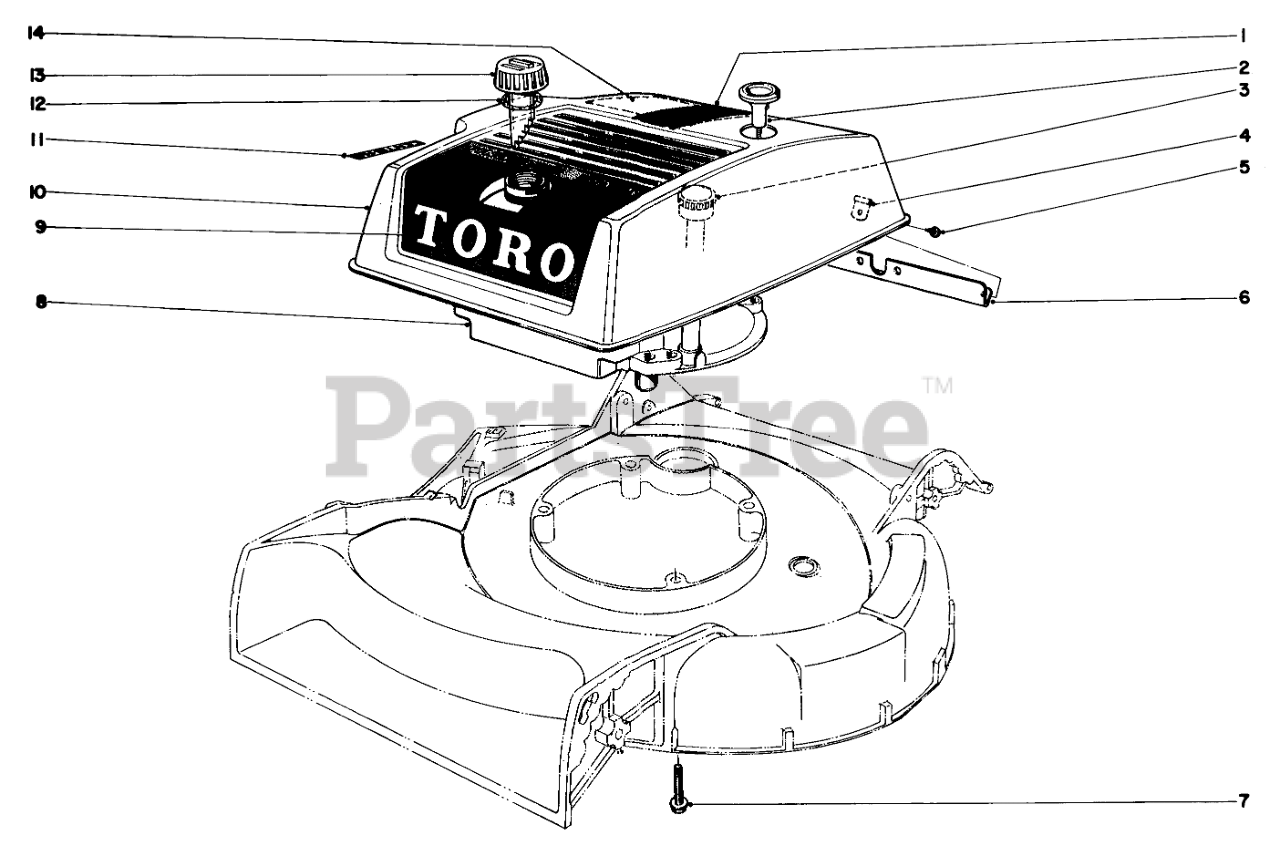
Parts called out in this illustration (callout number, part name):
1	Decal
2	Handle, Rope
3	Dip Stick
4	Hinge
5	SCREW-HWHTF
6	Shroud Bracket
7	3/8-16 X 2-3/4 CAPSCR
8	Engine
9	Decal
10	Shroud
11	Decal, Air Cleaner
12	Gasket
13	Gas Cap
14	Decal-Maintenance
